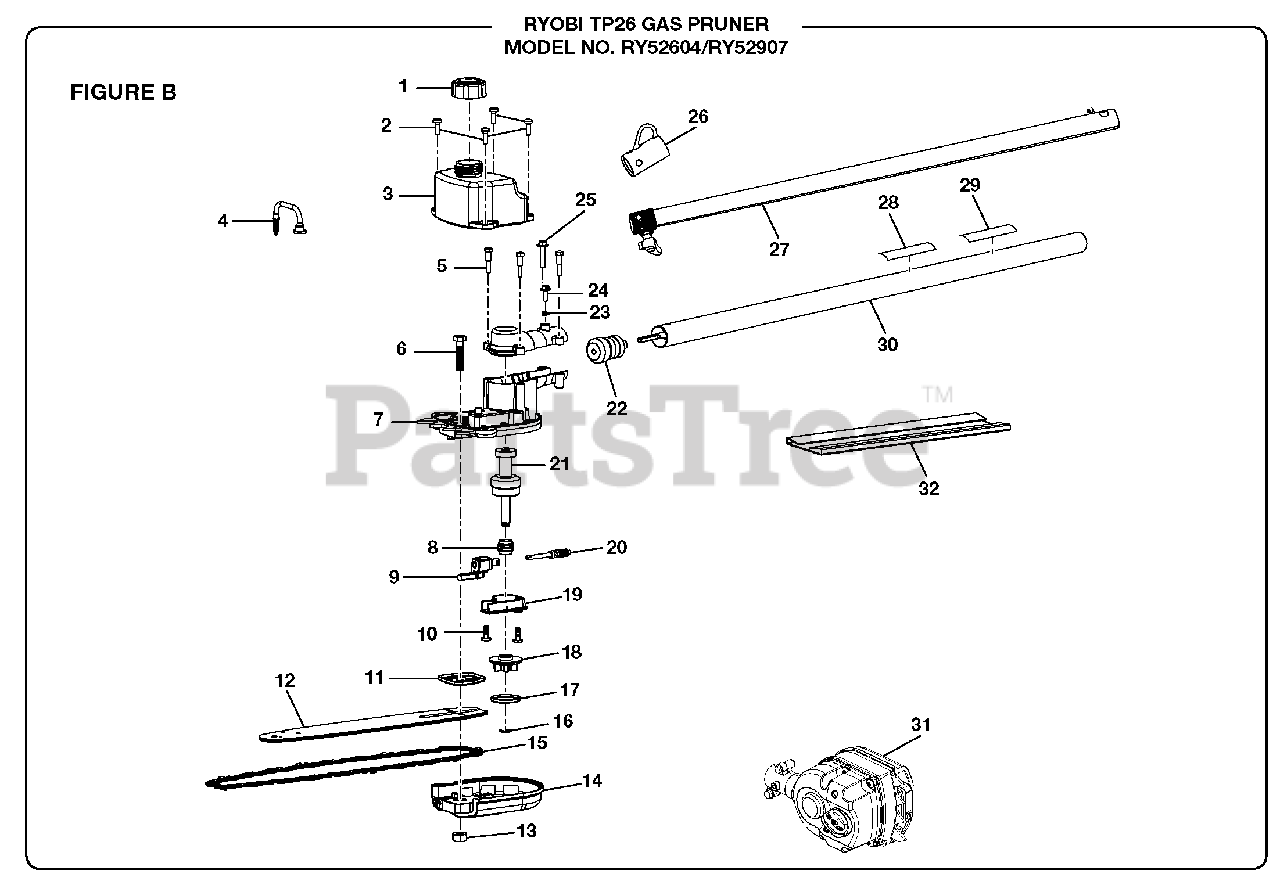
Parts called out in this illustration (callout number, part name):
1	Oil Cap Assembly
2	Screw (M5 x 18 mm)
3	Oil Tank Cover Assembly
4	Oil Pickup Assembly
5	Screw (M5 x 25 mm)
6	Screw (M8 x 35 mm)
7	Gear Case Assembly
8	Worm Gear
9	Oil Pump Seal Assembly
10	Screw (M5 x 13 mm)
11	Bar Pad Plate
12	Guide Bar
13	Hex Nut (M8)
14	Bar Clamp Assembly
15	Chain (10 in.)
16	E-ring (dia6 mm)
17	Cupped Washer
18	Sprocket
19	Oil Pump Housing w/Cam Pin Assembly
20	Pinion Gear & Plunger Assembly
21	Output Shaft Assembly
22	Pinion and Bearing Assembly
23	Lock Washer (5 mm)
24	Screw (M5 x 15 mm)
25	Screw (M5 x 25 mm)
26	Hanger Cap
27	Intermediate Boom Assembly
28	Logo Label
29	Warning Label
30	Lower Drive Shaft Assembly (Incl. Key No. 28-29)
31	Gear Head Assembly (Incl. Key Nos. 1-11, 13-14 and 16-25)
